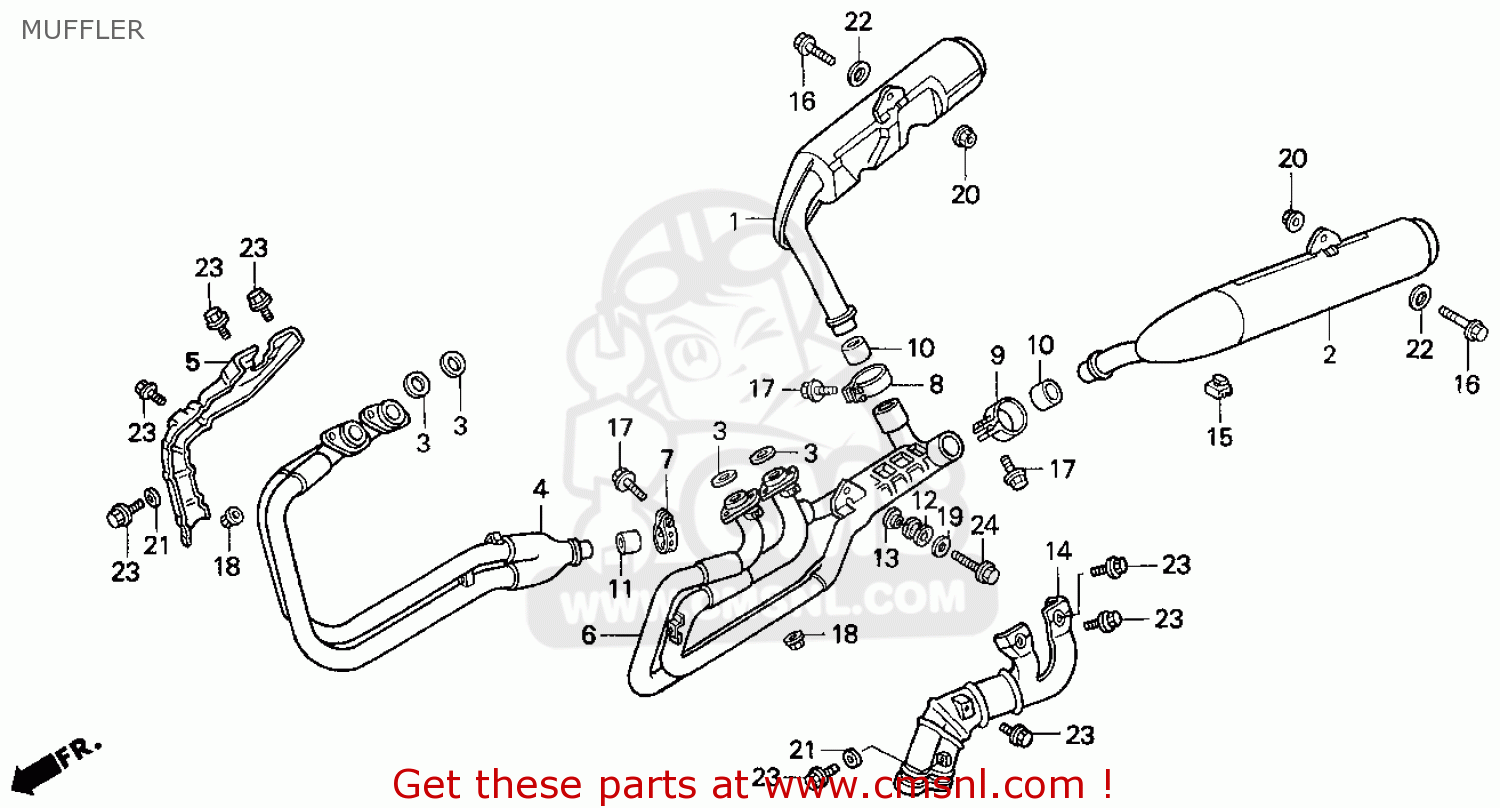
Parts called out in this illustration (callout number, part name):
1	MUFFLER ASSY,R
2	MUFFLER ASSY,L
3	GASKET,EX.PIPE (NAS)
4	PIPE COMP.,EXH.R
5	COVER,R.EX.PIPE
6	PIPE COMP.,EXH,L
7	BAND MUFFLER
8	BAND,R.MUFFLER
9	BAND L MUFFLER
10	PACKING,MUFFLER (NAS)
11	PACKING,MUFFLER (NAS)
12	RUB,MUFFLER MOUNT
13	COLLAR,MUFF.MOUT.
14	COVER,L.EX.PIPE
15	RUBBER A,STAND ST
16	BOLT,FLANGE,8X50
17	BOLT,FLANGE 8X40
18	NUT,FLANGE,7MM
19	WASHER,8.5X26
20	NUT,FLANGE,8MM
21	WASHER PLAIN 6MM
22	WASHER,PLAIN,8MM
23	BOLT,FLANGE,6X10
24	BOLT,FLANGE,8X45
